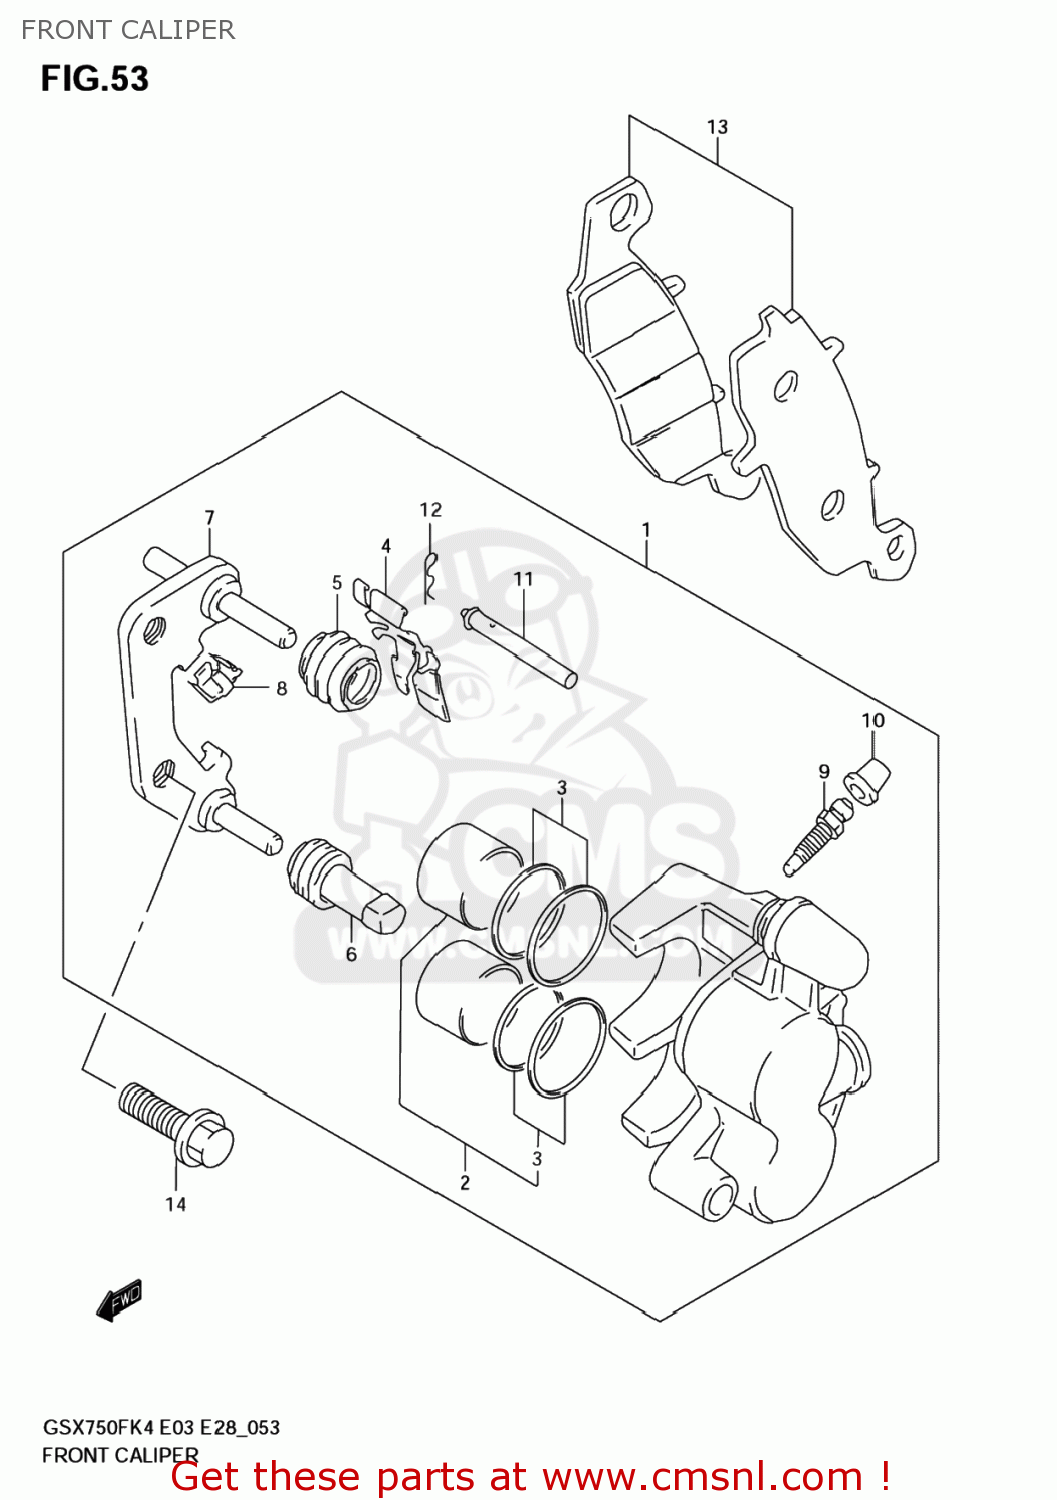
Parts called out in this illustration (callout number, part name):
1	CALIPER ASSY, FRONT RH
2	PISTON SET
3	SEAL SET,PISTON
4	SPRING,PAD,R
5	BOOT,AXLE
6	INSULATOR,AXLE
7	CARRIER,CALIPER,R
8	GUIDE,PAD
9	BLEEDER
10	CAP,BLEEDER PLUG
11	PIN,PAD
12	CLIP,PAD PIN
13	PAD SET,R (NAS)
14	BOLT
